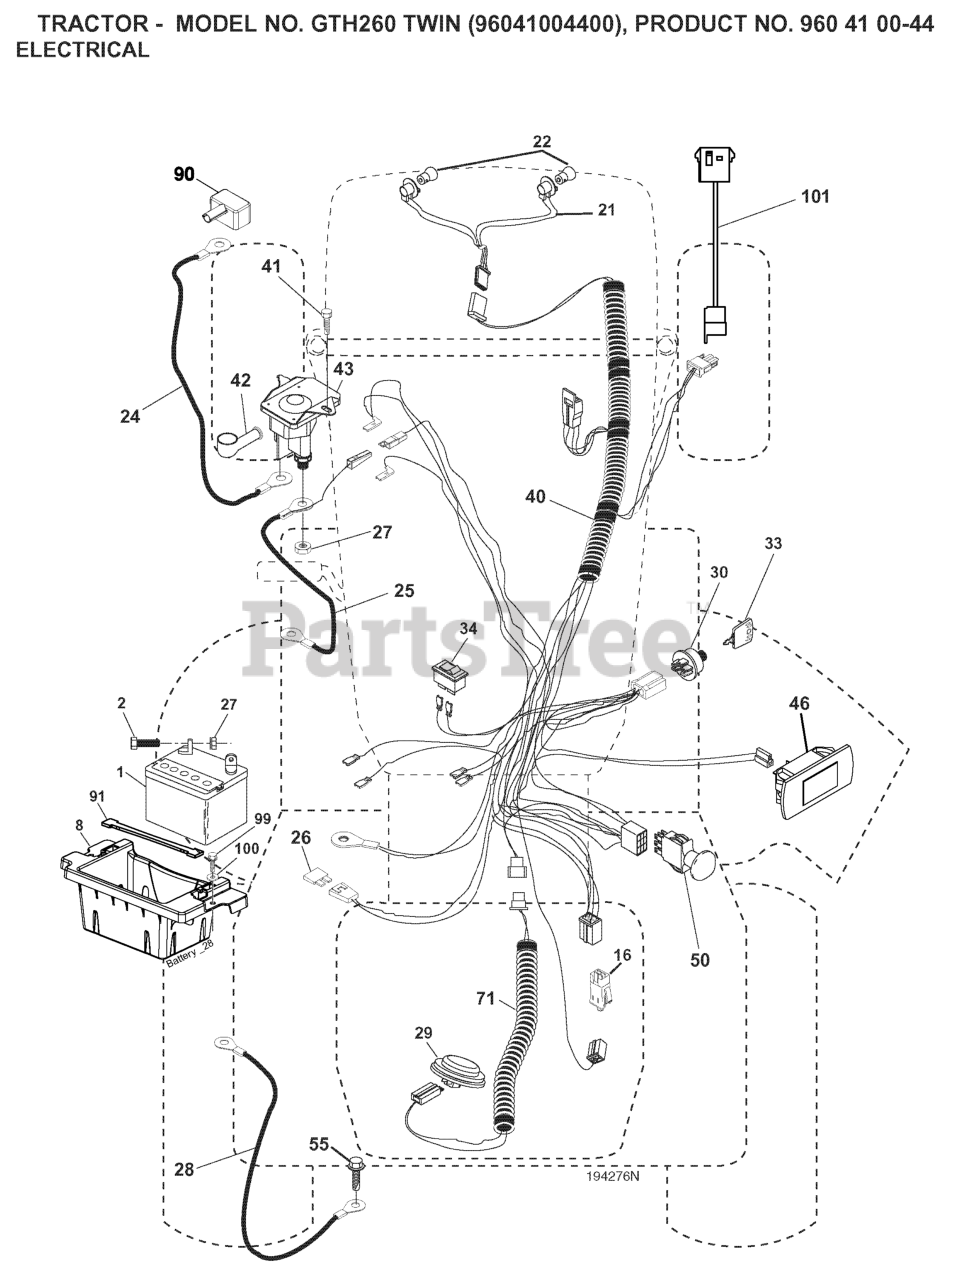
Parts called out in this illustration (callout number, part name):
1	BATTERY 12V .35 AMP
2	BOLT.HEX.1/4.X.3/4.DICHROMATE
8	BOX.BATTERY.MOUNT.FRONT.LT
16	SWITCH INTERLOOK PUSH-IN
21	HARNESS ASSY LIGHT
24	CABLE.BATT.POS.WIRE.TG.DA SOL
25	CABLE.START.RED.17.5".
26	FUSE 20AMP
27	NUT
28	CABLE GROUND 6 GA 21" 90T BLK
29	SWITCH.SEAT.DELTA.OPC.
30	SWITCH.IGN.DELTA.W.LGH.ROS
33	KEY MLD GEN DELTA
40	HARNESS.IGN.DASH.HUQ/P
41	SCREW
42	TERMINAL COVER
43	SOLENOID.W/BRASS.PLUNGER
46	RP.GUAGE.SRVCMNDR.HRMTR.
50	RP.PTO.SWITCH.8 TERMINAL.BLACK
55	Screw 5/16-18 x 1/2 Hex, Self Tapping 5/16-18 x 1/2
71	HARNESS-CHASSIS SUB
90	COVER.TERMINAL.BATTERY
91	STRAP.BATTERY.MOUNT.FRONT(2 2)
99	SCREW HEXWSHR 1/4-20X3/4
101	PIGTAIL.MATNLK.NEW.HAR
